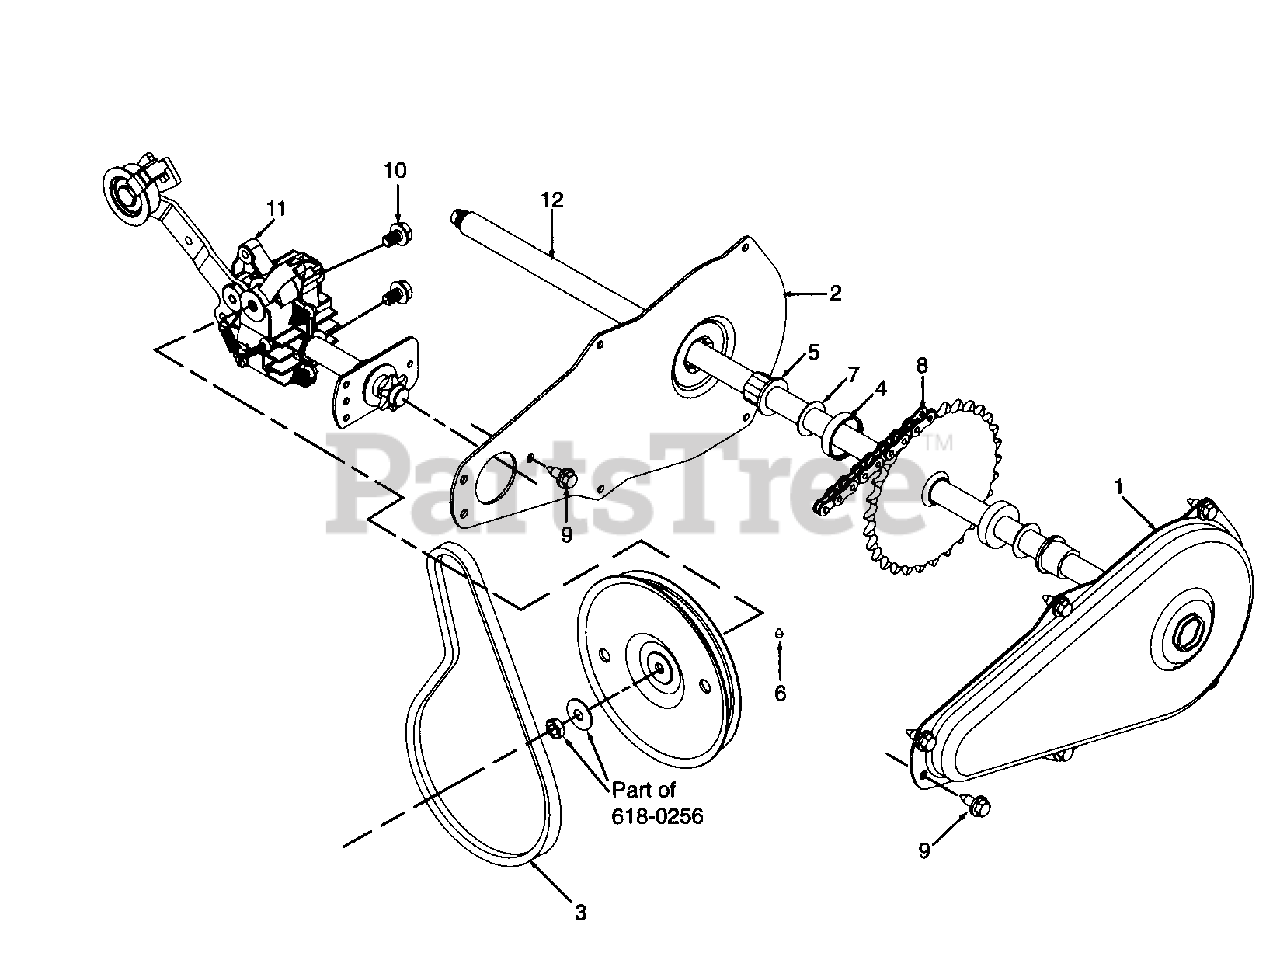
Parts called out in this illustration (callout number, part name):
3	V-BELT 3/8 x 24.68
4	SPACER .630 x 1.25 x .290
5	HEX FLANGE BEARING .631 x .720
6	BEALENE GREASE
7	FLAT WASHER 5/8 x 1.00 x .03O
8	CHAIN #41 x .500
9	HEXWASH HD. AB-TAP SCREW 1/4-20 x .625"
10	HEX WASH HD. TYPE B SCREW 5/16-18 x .50"
11	TRANSMISSION ASS'Y. (SEE DETAIL ABOVE)
12	SHAFT: AXLE ASSEMBLY
